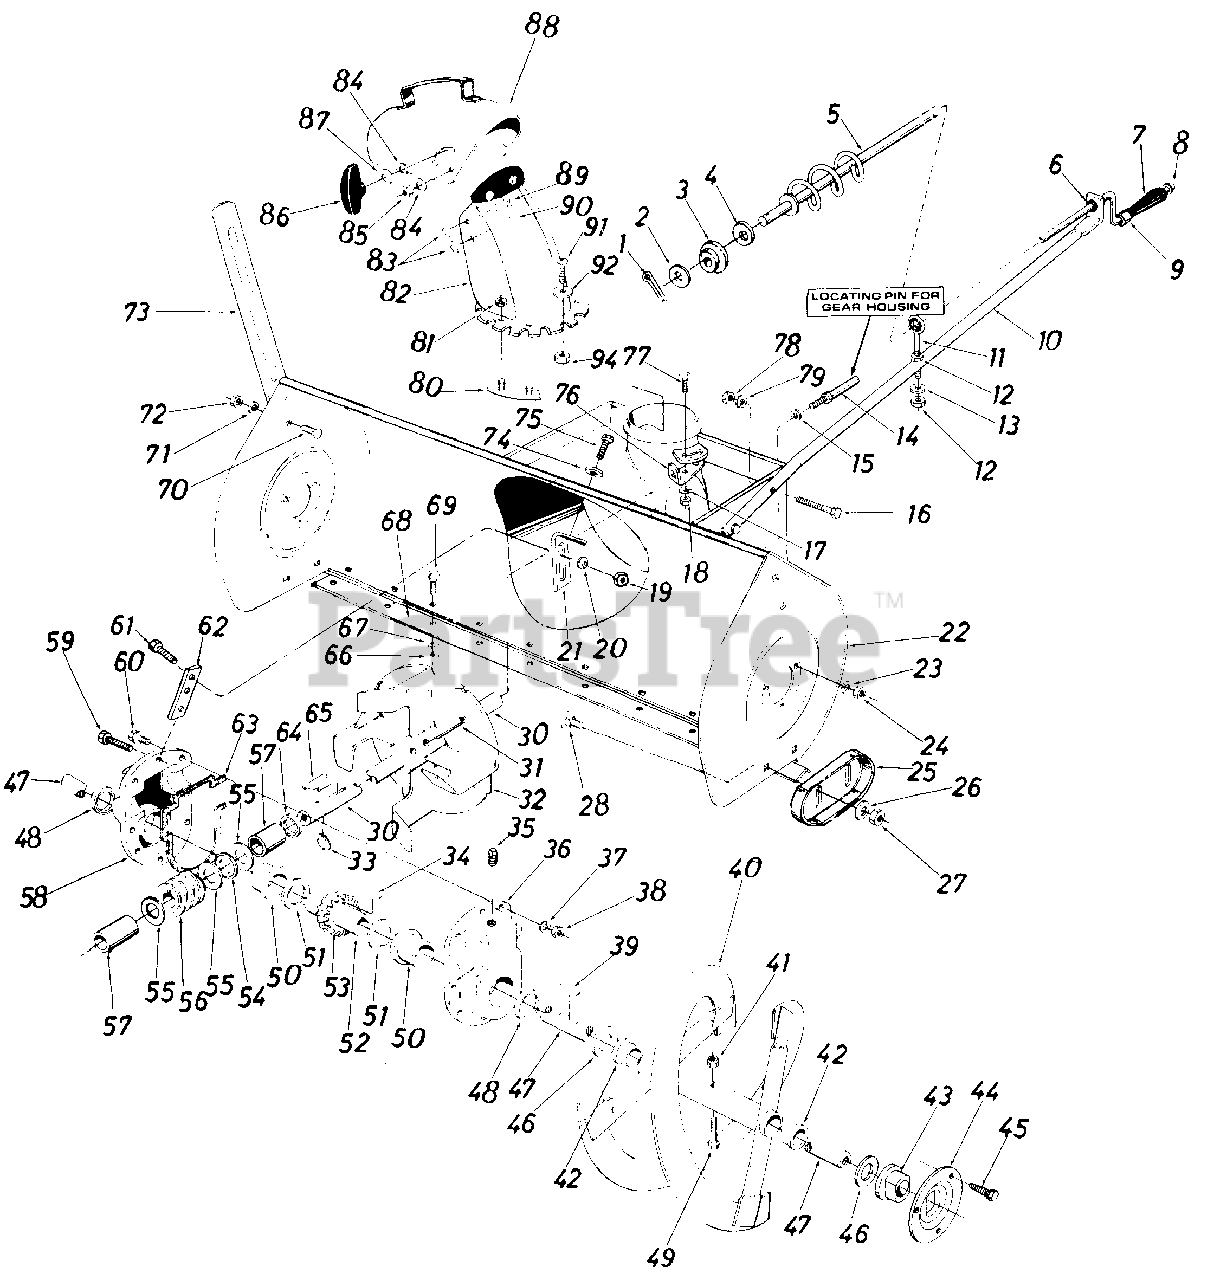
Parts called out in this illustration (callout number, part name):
1	Cotter Pin
2	Fl.-Wash. .39" I.D. x .62" O.D.
3	Plastic Bushing
4	Fl.-Wash. .385" I.D. x .62" O.D.
5	Chute Crank Ass'y.
6	Plastic Bushing
7	Knob Ball 3/8" Dia. Hole
8	Push Nut 3/8" Rod
9	Spacer.385 I.D. x .50" I.D.
10	Chute Crank Support Tubing
11	Eyebolt
12	Hex Nut 5/16-18 Thd.*
13	Bell.-Wash. .345" I.D. x.88"O.D.
14	Stud 3/8-16 x 2.75" Lg.
15	Bell.-Wash. .400" I.D. x .88"O.D.
16	Hex Bolt 3/8-24 x 1.25" Lg.*
17	Bell.-Wash. .345" I.D. x .88"O.D.
18	Hex Nut 5/16-18 Thd.*
19	Hex ut 1/4-28 Thd .
20	Bell.-Wash. .265" I.D. x .75"O.D.
22	45 " Snow Blower Housing Ass'y.
23	L.-Wash. 5/16" I.D.*
24	Hex Nut 5/16-18 Thd.*
25	Slide Shoe
26	Bell.-Wash. .400" I.D. x .88"O.D.
27	Hex Jam Nut 3/8-16 Thd.
28	Carriage Bolt 3/8-16x .62" Lg.*
30	Blower Axle .875" Dia. x 14.75" Lg.
31	Spring Pin Spir. 5/16" Dia. x 1.75" Lg.
34	#91 Woodr-Key 1/4 x 3/4" Dia. (HDN)
35	Vent Plug
36	Comp. Gear Hsg. Half-L.H.
37	Spr.-Wash. .32 " I.D. x .62" O.D.
38	Hex Ins. L.-Nut 5/16-18 Thd.
39	#91 Woodr-Key 1/4 x 3/4" Dia. (HDN)
41	Hex Ins. L.-Nut 5/16-18 Thd.
42	Plastic Bushing
43	Flange Brg. w/flats 1" I.D.
44	Bearing Housing
45	Hex Sems Bolt 5/16-18 x .75" Lg.*
46	Fl.-Wash. 1.00" I.D. x 1.75" O.DI.
47	Spiral Axle
48	Flange Bearing 1.503" I.D.
49	Shear Bolt 5/16-18 x 1.75" Lg.
50	Oil Seal 1.50" I.D.
51	Fl.-Wash. 1.50" I.D. x 2.00" O.D
52	Worm Gear Shaft
53	Double Threaded Worm Gear -L. H .
54	Thrust Brg. - .88" I.D. x 1.44"O.D.
55	Fl.-Wash. .88" I.D. x 1.4" O.D.
56	Double Threaded Worm - L.H.
57	Sleeve
58	1 Complete Gear Hsg. Half - R.H.
59	Hex Bolt 5/16-18x 1.25" Lg.*
60	Hex Bolt 5/16-18 x 1.0" Lg. (Grade 5)
61	Hex Bolt 1/4-28 x .75" Lg.
62	Gear Housing Support Plate
63	Rubber Gasket
64	Oil Seal - .875" I.D.
65	#9 Hi-Pro Key 3/16 x 3/4" Dia. (HT.)
66	Hex Nut 5/16-18 Thd.*
67	L.-Wash.5/16" I.D.*
69	Carriage Bolt 5/16-18 x 1.00" Lg.*
70	Carriage Bolt 5/16-18 x .62" Lg.*
71	L.-Wash. 5/16" I.D.*
72	Hex Nut 5/16-18 Thd.*
73	Guide Blade
74	Bell.-Wash. .345" I.D. x .88" O.D.
75	Hex Wash. Hd. AB Tap Scr 5/16 x .75" Lg.
77	Carriage Bolt 5/16-18 x .75" Lg.*
78	Hex Ins. L.-Nut 3/8-24 Thd.
79	L.-Wash. 3/8" I.D.*
80	Chute Flange Keeper
81	Hex Cent. L.-Nut 1/4-20 Thd.
82	Chute Ass'y. w/Chute Guard
83	Fl.-Wash. .285" I.D. x 1.25" O.D.
84	Bell.-Wash. .345" I.D. x .88" O.D.
85	HexCent. L.-Nut5/16-18 Thd.
86	Knob Handle
87	Bell.-Wash. .345" I.D. x .88" O.D.
88	Top Chute Ass'y.
89	Carriage Bolt 5/16-18 x 1.00" Lg.*
90	Carriage Bolt 5/16-18 x .62" Lg*
91	Truss ach. Scr. 1/4-20 x .50
92	Fl.-Wash. .285" I.D. x 1.25" O.D.
94	Hex Cent. L-Nut 1/4-20 Thd.
